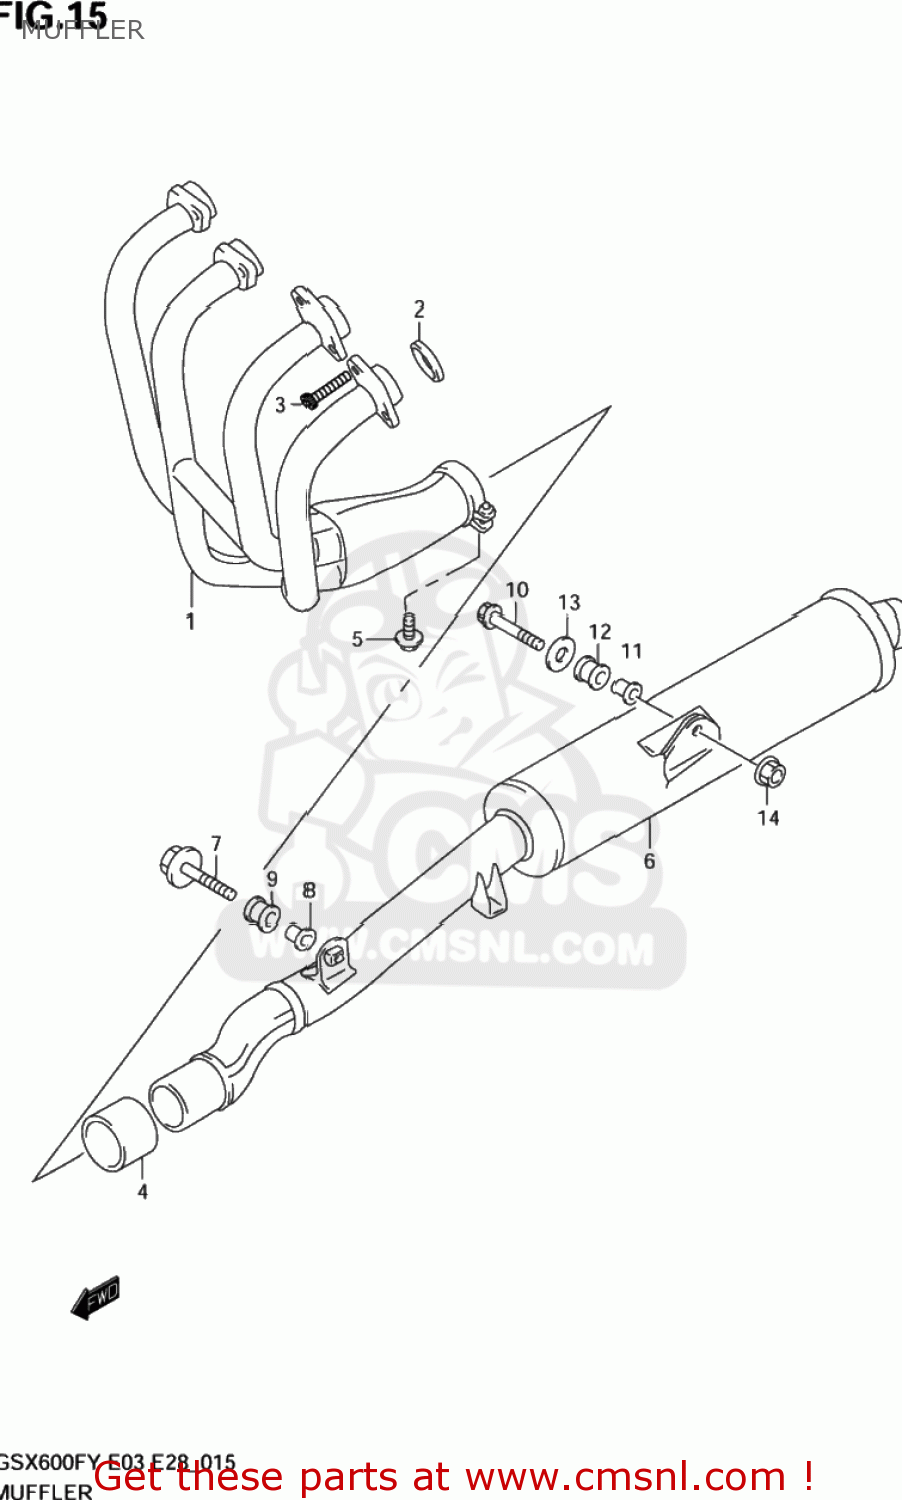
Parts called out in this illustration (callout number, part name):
1	EXHAUST COMP
2	GASKET,EXHAUST (NAS)
3	BOLT
4	CONNECTOR,MUFFLER
5	BOLT
6	BODY,MUFFLER
7	BOLT 8X40
8	SPACER(8.6X12X24.2)
9	CUSHION
10	BOLT
11	SPACER(8.6X12X27.1)
12	CUSHION
13	WASHER (8.5X33X1.6)
14	NUT
